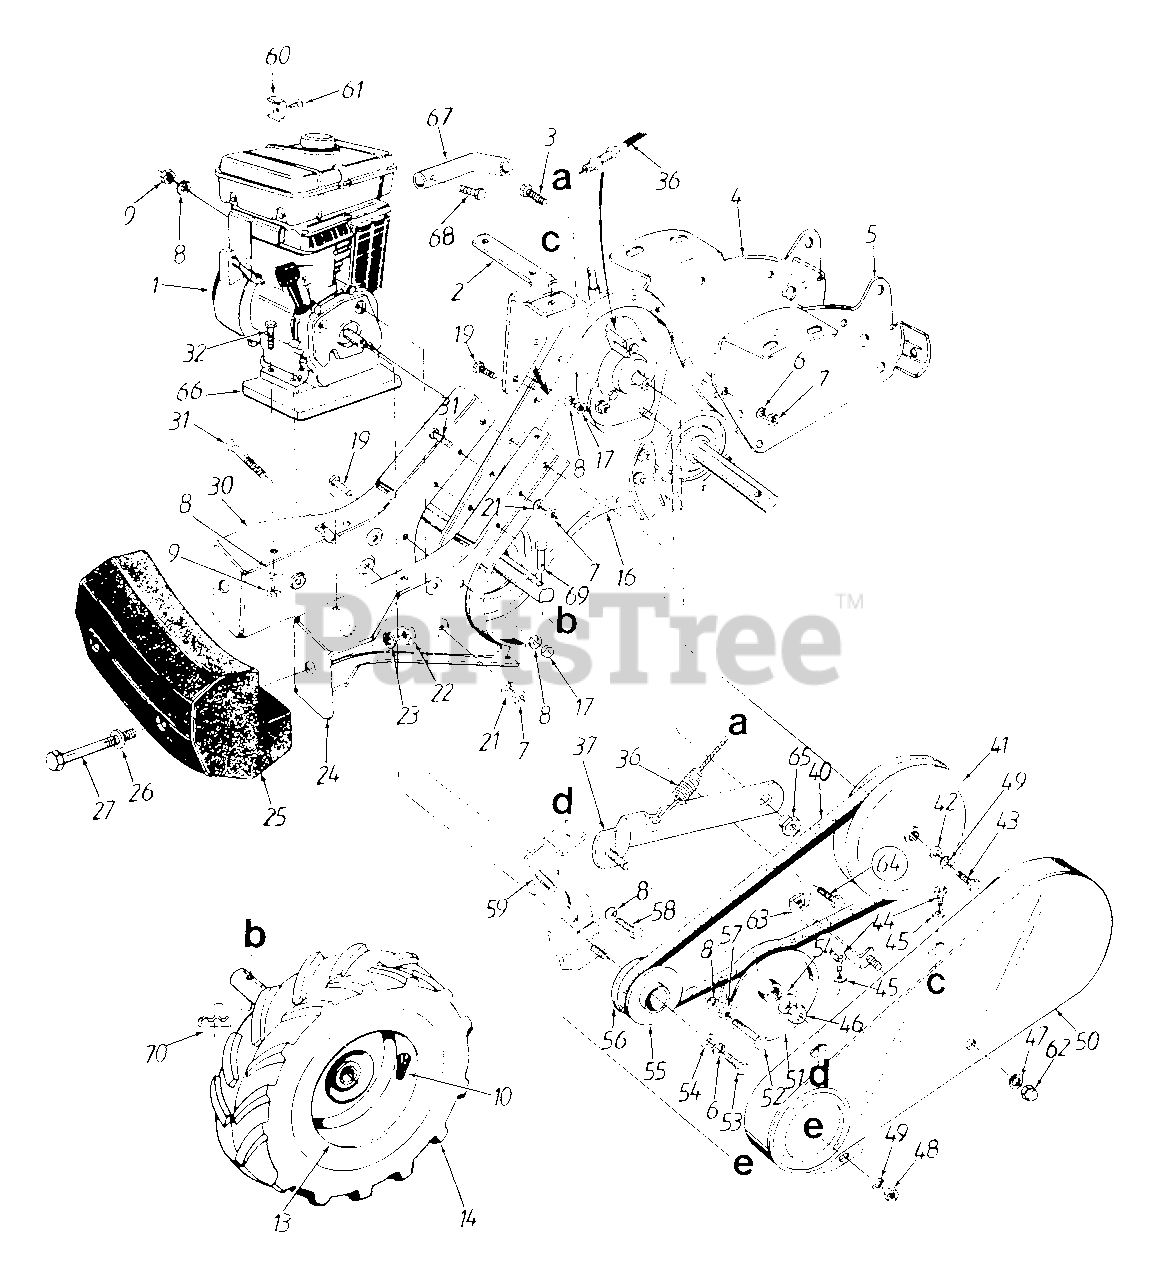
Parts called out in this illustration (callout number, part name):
1	Engine
2	Shift Cover Mounting Brkt.
3	Hex Bolt 3/8-16 x 1.00" Lg.
6	L-Wash. 3/8" I.D.
7	Hex Nut 3/8-16 Thd.
8	L-Wash. 5/16" I.D.
9	Hex Nut 5/16-18" Thd.
10	Air Valve
10	Hex Bolt 5/16-24 x .62" Lg.
10	Bell - Wash..345" I.D. x .88"
16	Gear Case Ass'y. Comp.
17	Hex Nut 5/16-18 Thd.
19	Hex Bolt 5/16-18 x .75" Lg.
21	L-Wash. 3/8" I.D. - H.D.
22	Hex Nut 1/2-13 Thd.
23	L-Wash. 1/2" I.D.
26	Fl-Wash. .510" I.D. x 1.0"
27	Hex Bolt 1/2-13 x 5.00" Lg.
32	Hex Bolt 5/16-18 x 2.75"
36	Clutch Control Cable 46" Lg.
37	Idler Bracket Ass'y.
40	V - Belt
41	Fl-Pulley 8" O.D.
42	Fl-Wash 1/4" I.D. x .93" O.D.
43	Hex Bolt 1/4-28 x 75" Lg.
44	Hex Wash. Hd. S-Tap Scr. 1/4-20 x 50" Lg.
45	Fl-Wash. .281" I.D. x .625"
46	Hex Cent. L-Nut 3/8-24 Thd.
47	Fl-Wash. .266" I.D. x .625" O.D.
48	Hex Nut 1/4-20 Thd.
51	Fl-Idler w/Flanges 3.75" O.D.
52	Hex Bolt 5/16-24 x 1.75"
53	Hex Bolt 3/8-24 x 1.00" Lg.
54	Fl-Wash 3/8" I.D. x 1.00"
55	Outer Engine Pulley Half
56	Inner Engine Pulley Half
57	Hex Nut 5/16-24 Thd.
58	Hex Bolt 5/16-24 x .62" Lg.
59	Belt Keeper Ass'y.
60	Casing Clamp
61	Hex Sems Scr. #10-32 x .62"
62	Hex Cap Nut 1/4-28 Thd.
63	Belt Cover Brkt. Ass'y.
64	Hex Bolt 5/16-18 x 1" Lg. (Gr. 5)
65	Shld. Nut
66	Engine Spacer Block
67	Outlet Pipe
68	Hex Wash. Hd. AB-Tap Scr. #8 x .5" Lg.
69	Clevis Pin
70	Hairpin Clip
